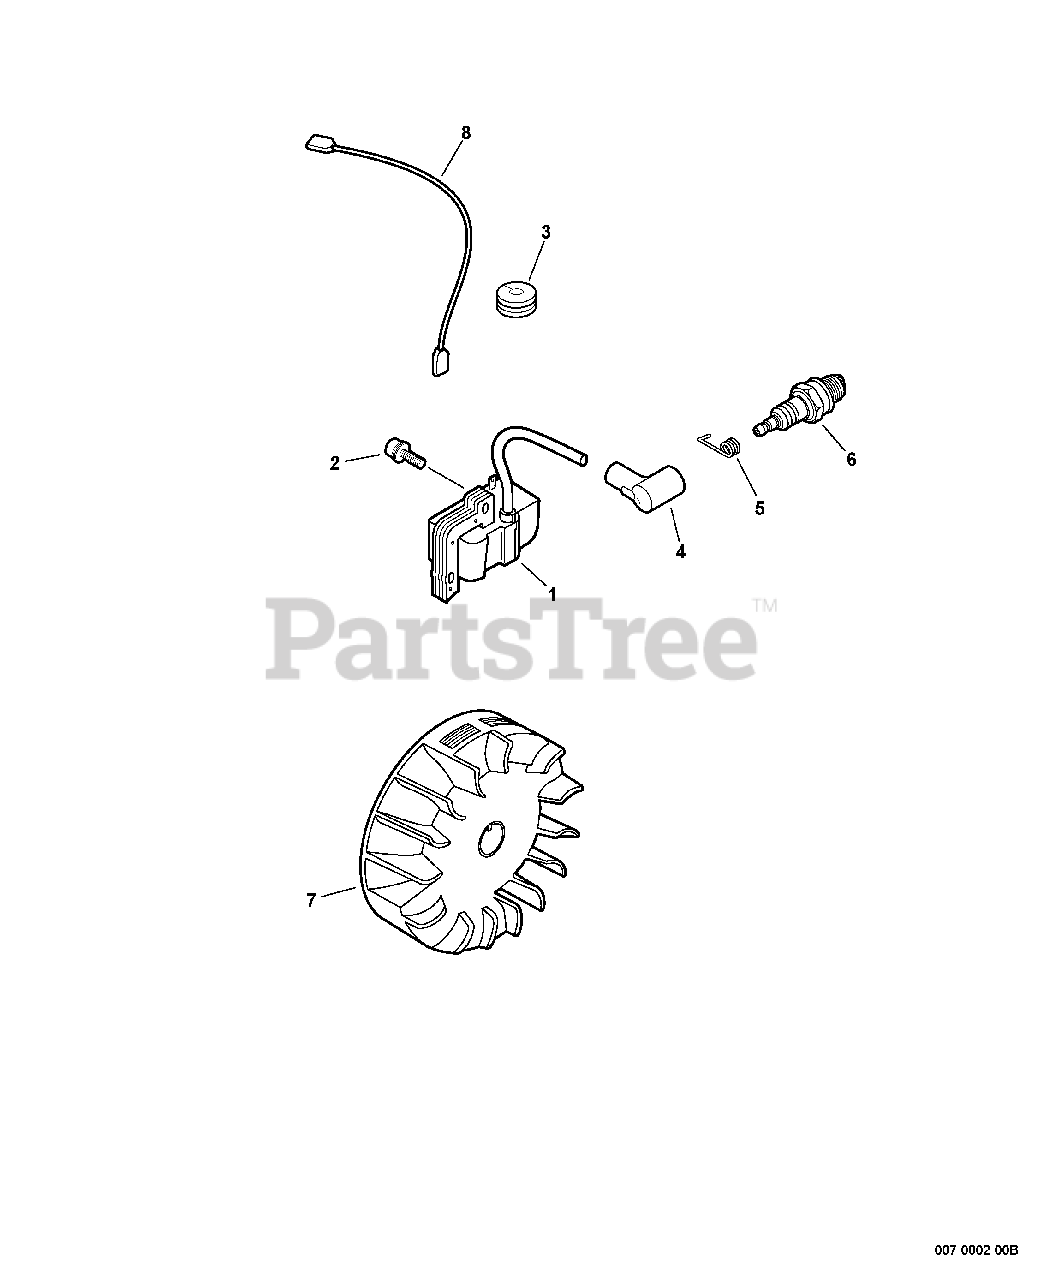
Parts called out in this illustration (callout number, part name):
1	COIL, IGNITION
2	SCREW 4×22
4	CAP, SPARK PLUG
5	TERMINAL, SPARK PLUG
6	SPARK PLUG - BPM7A
8	LEAD
